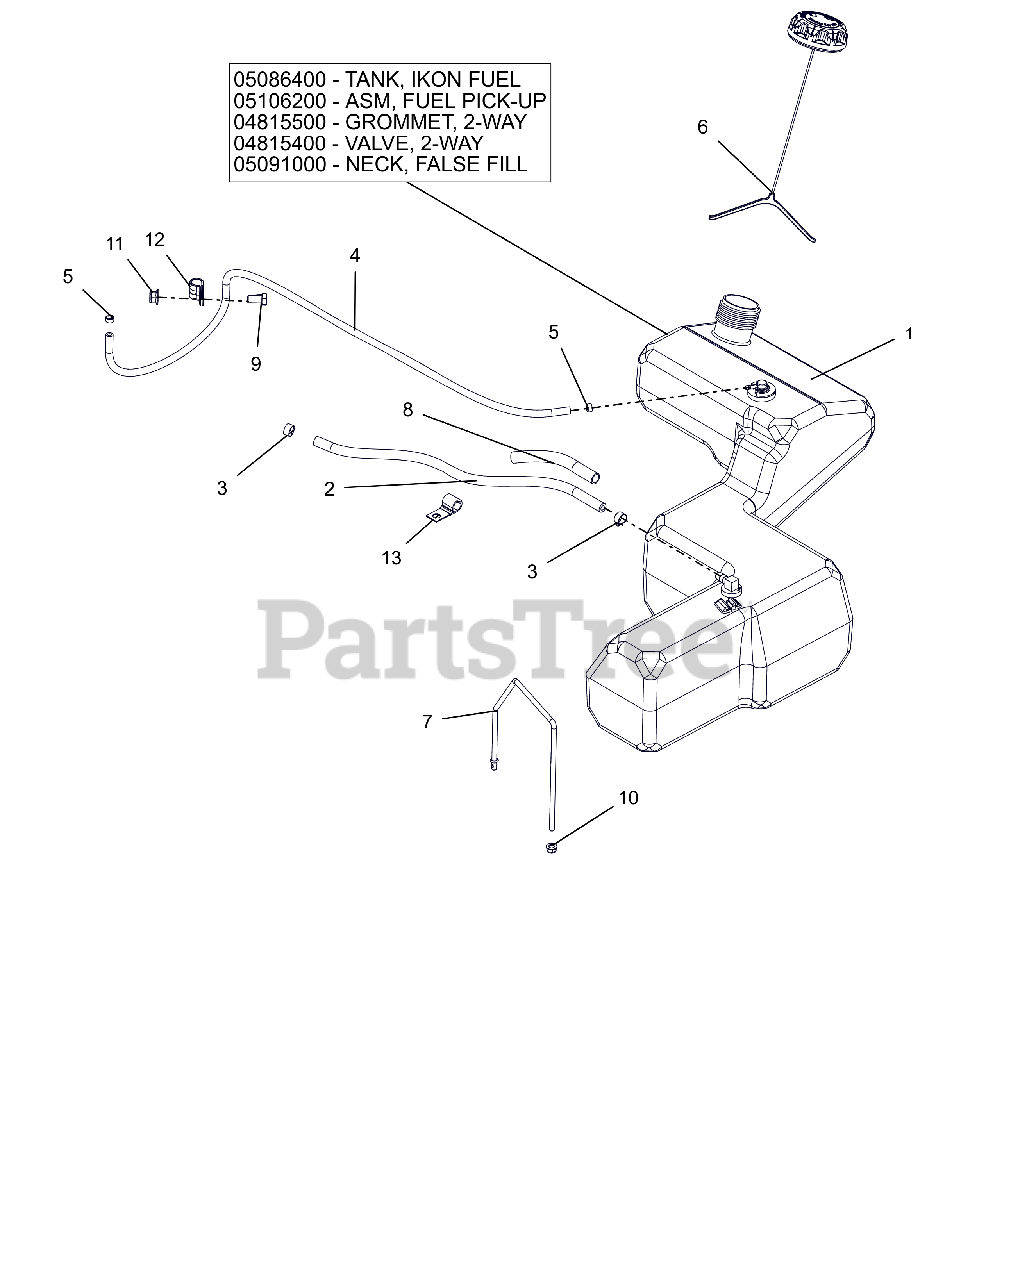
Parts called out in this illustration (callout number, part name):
1	ASSEMBLY, FUEL TANK IKON(2017)
1	TANK, IKON FUEL (2017)
1	ASM, IKON FUEL PICK-UP
1	GROMMET, 2-WAY
1	VALVE, 2-WAY
1	NECK, FALSE FILL-2017 IKON
2	HOSE, .25 LOW-PERM BULK GAS
3	CLAMP, FUEL LINE
4	HOSE, .188 LOW-PERM BULK GAS
5	CLAMP-HOSE, SPRING .188
6	CAP, FUEL VENT-IN 2.25" RATCH.
7	BRKT, FUEL TANK HOLD DOWN
8	WRAP, ANTIABRASION .5X.064WALL
9	@BLT-HEX .38-16X.75 GR5 YWZC
10	@NUT-LK-NYL-FLG .25-20 YWZC
11	@NUT-LK-NYL-FLG .38-16 YWZC
12	CLAMP, CUSHIONED STEEL
13	J-CLAMP
